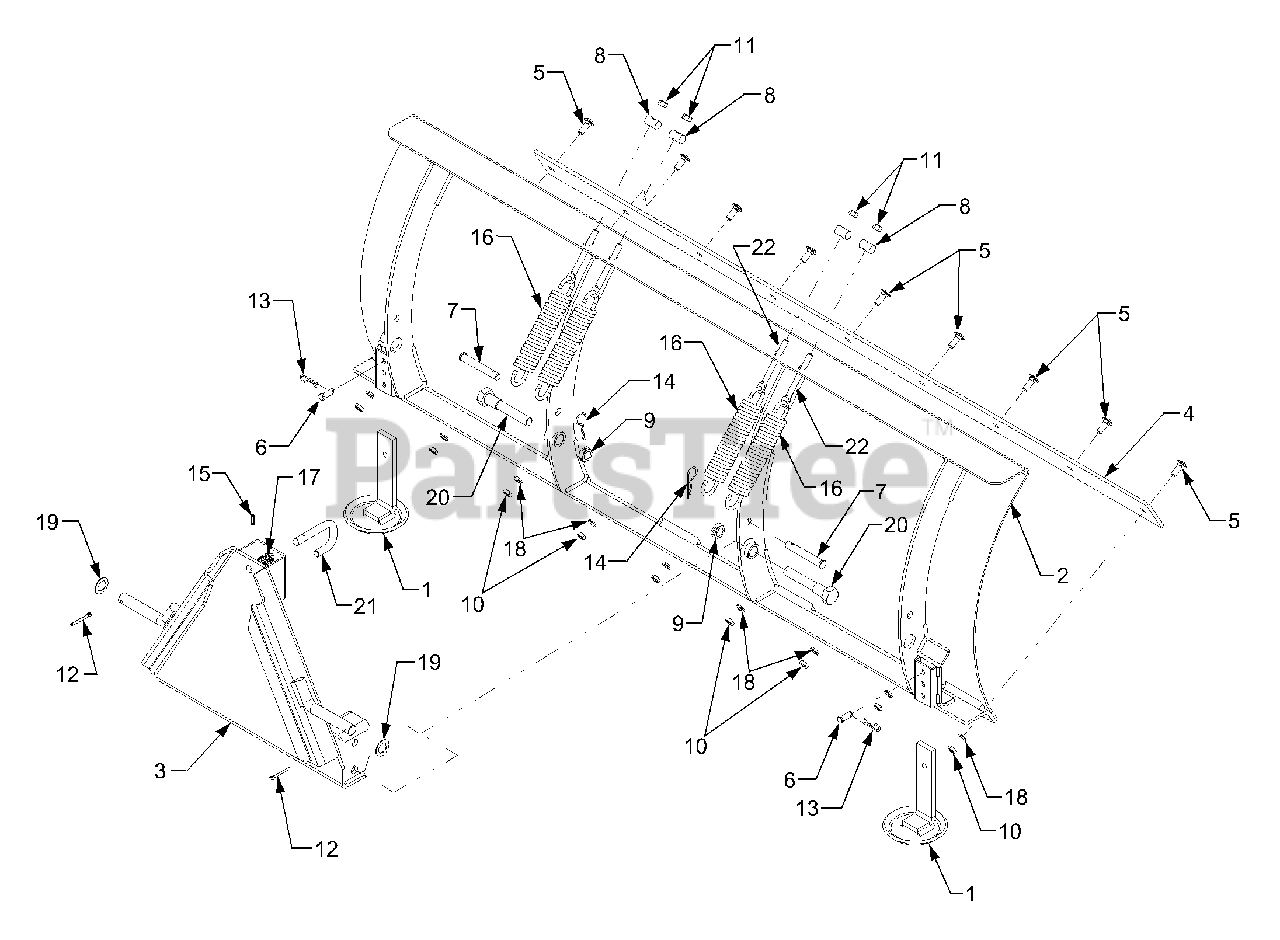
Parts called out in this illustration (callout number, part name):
6	Pin, Clevis, .375 x .969
7	Pin, Clevis
8	Spring Roller
9	Nut, Jam Lock, 5/8-11
10	Nut, Jam, 3/8-16 GR5
11	Nut, Hex, 3/8-16 GR8
12	Pin, Cotter, 3/16 x 1.5
13	Pin, Internal Cotter, .092 x 1.64
14	Pin, Internal Cotter
15	Pin, Spirol 3/16 x 3/4
16	Spring, Extension, 1.5 x 8.0
17	Spring, Compression, .57 x 2.09
18	Washer, Lock, 3/8
19	Washer, Flat, 793 x 1.24 x .06 Hdn.
20	Screw, Shoulder
21	Pin, Front Hitch
22	Rod, Spring Adjustment
